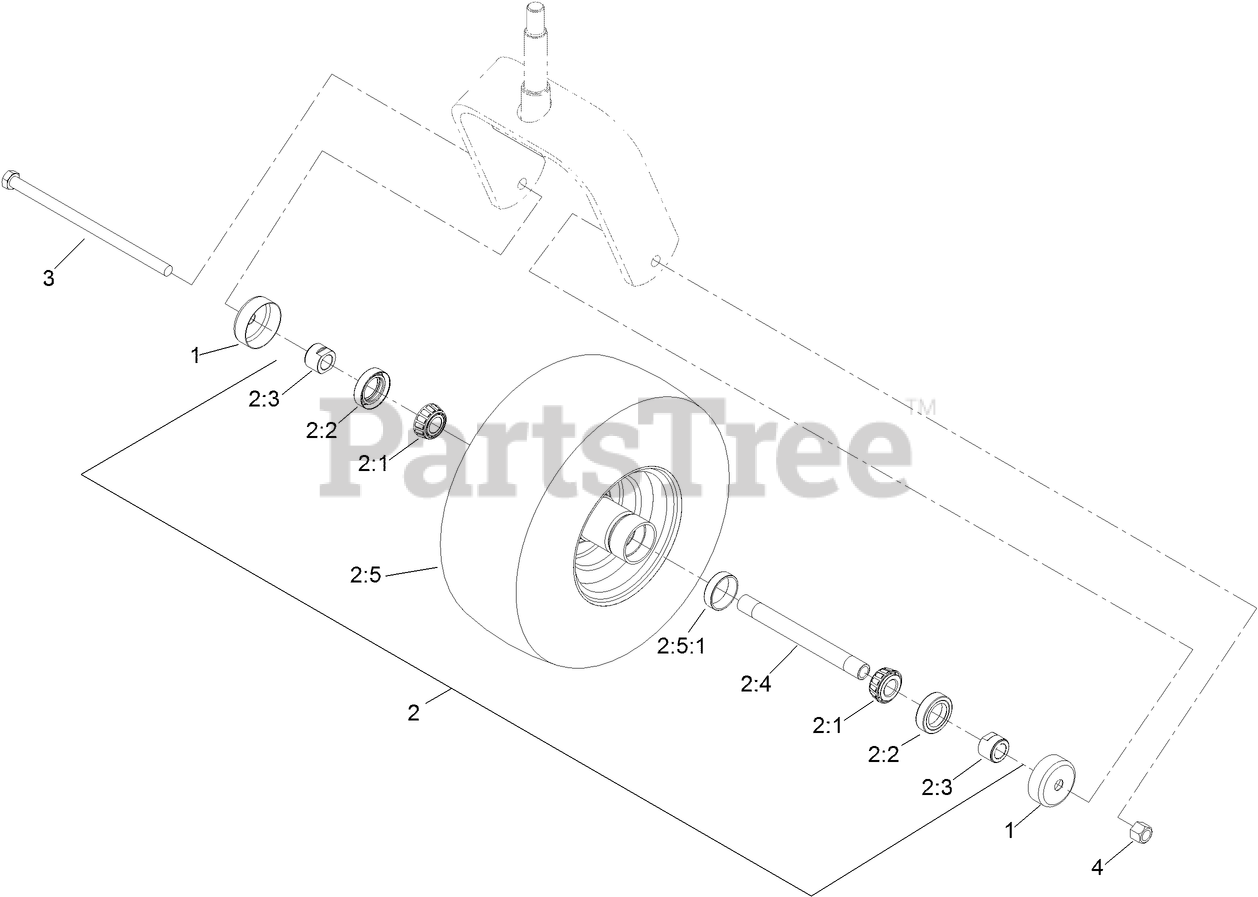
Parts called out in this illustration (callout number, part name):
1	GUARD-SEAL
2	WHEEL AND TIRE ASM
2:1	BEARING-CONE, TAPER
2:2	SEAL-CASTER
2:3	SPACER-NUT
2:4	Axle-Caster
2:5	WHEEL AND TIRE ASM
2:5:1	BEARING-CUP
3	Screw-HH
4	NUT-LOCK, NI
